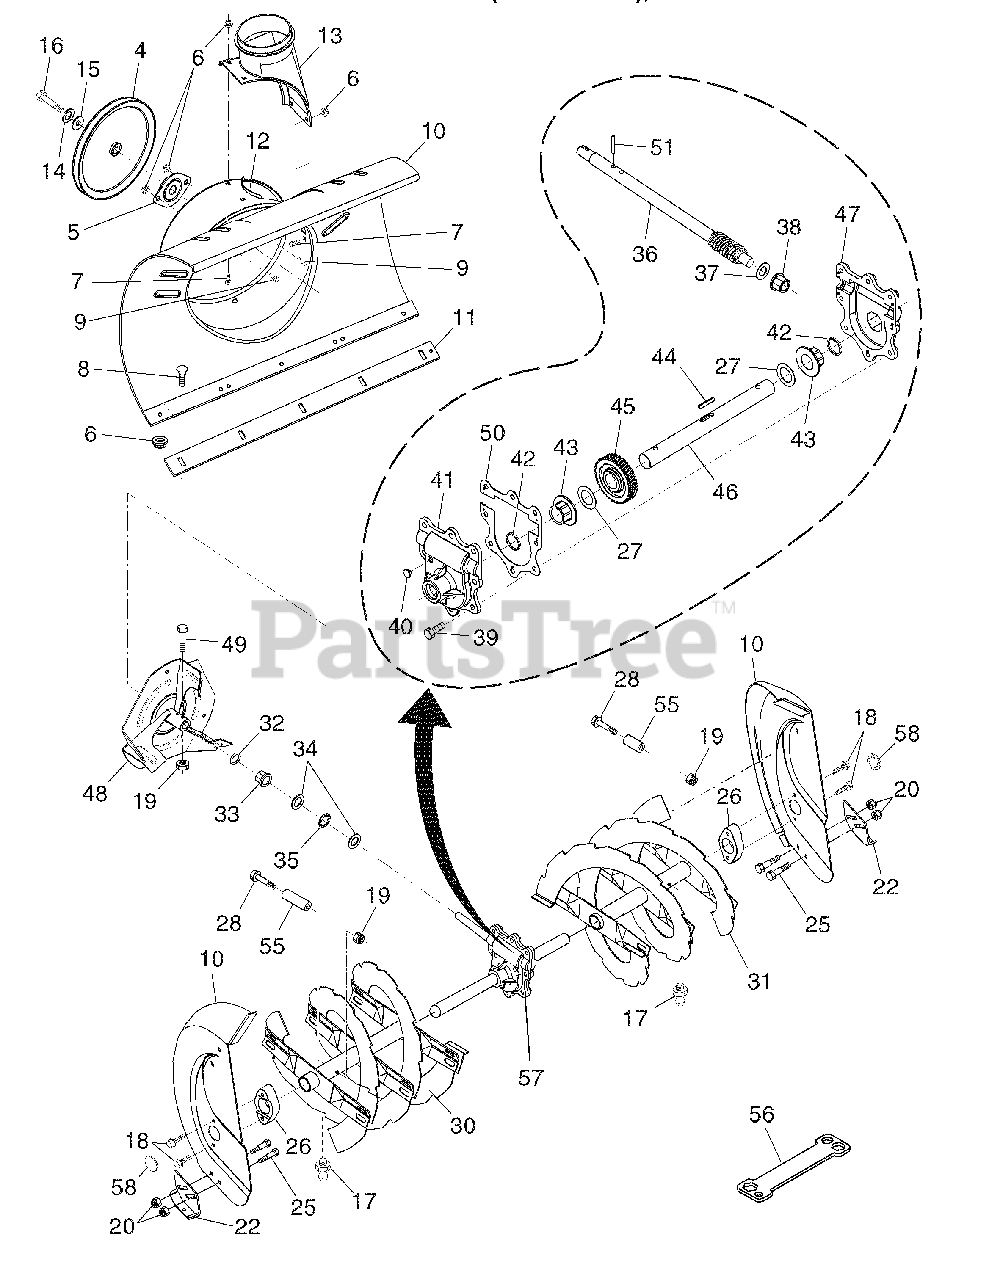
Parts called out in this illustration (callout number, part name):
4	Pulley, Impeller
5	Bearing Assembly, Flange
6	Nut, Hex Flange 5/16-18
7	Bolt, Flat Head, Carriage 5/16-18 x 5/8
8	Bolt, Carriage 5/16-1 8 x 5/8
10	Housing, Auger
11	Bar, Scraper
12	Bracket, Corner Discharge
13	Base, Discharge Chute
14	Washer, Lock 5/16
15	Washer, Flat
16	Cap Screw HXHD 5/16-18 x 1
17	Grease Fitting
18	Screw, Hex Head 5/16 x 1
19	Nut, Hex Lock 1/4-20
20	Nut, Hex Lock 5/16-18
22	Skid Plate, Heavy Duty
25	Bolt, Shoulder 1/4-20
26	Bearing, Auger
27	Washer, Thrust, 1"
28	Bolt, Shear
30	Auger Assembly, RH
31	Auger Assembly, LH
33	Bushing, Flange 3/4
34	Washer, Thrust 3/4
35	Bearing, Thrust 3/4
36	Shaft, Impeller
37	Washer, Thrust 5/8
38	Bushing, Flange 5/8
39	Screw, Hex Head 5/16-18 x 3/4
40	Plug, Case
41	Housing, Gearbox, RH
42	Seal, Oil
43	Bushing, Flange, 1"
44	Key, Square 1/4 x 1/4 x 7/8
45	Gear, Worm
46	Shaft, Auger
47	Housing, Gearbox, LH
48	Impeller Assembly
49	Screw, Hex Head 1/4-20 x 1-5/8
50	Gasket, Gearbox
51	Pin, Roll 3/16 x 1-1/8
56	Multi-Wrench
57	Gearbox Assembly
58	Plug Bearing Hole
